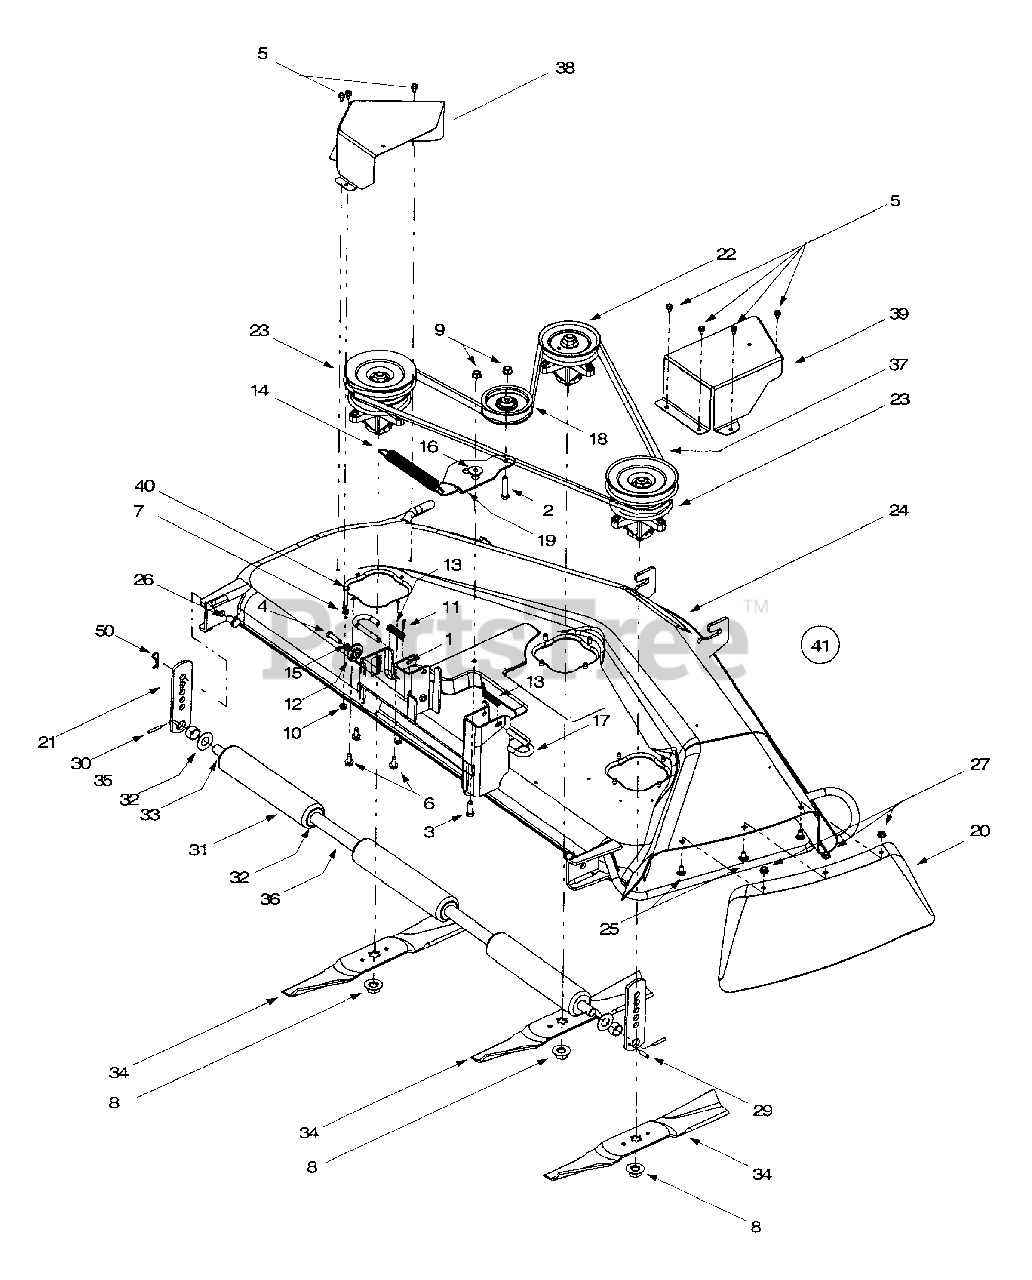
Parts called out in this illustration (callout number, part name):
1	Carriage Screw, 1/4-20 x .5
2	Hex Cap Screw, 3/8-16 x 1.75
3	Hex Cap Screw, 3/8-16 x 1.0
4	Hex Cap Screw, 5/16-18 x 1.25
5	Self Tapping Screw, 1/4-20 x .5
6	Self Tapping Screw, 5/16-18 x .75
7	Center Lock Nut, 1/4-20
8	Hex Flange Nut, 5/8-18
9	Flange Lock Nut, 3/8-16
10	Hex Flange Lock Nut, 1/4-20
11	Internal Cotter Pin, .072 x 1.12
12	Deck Adjustment Gear
13	Compression Spring, .406 x .531 x 1.75
14	Extension Spring, .91 x 7.33
15	Lock Washer, 5/16
16	Shoulder Spacer, .625 x .169
17	Deck Release Pin
18	Flat Idler Pulley, 3.5 OD
22	Center Spindle Assembly, 5 Dia.
23	Double Pulley Spindle Assembly
26	Clevis Pin, .50 Dia. x .78
27	Hex Flange Lock Nut, 5/16-18 (Grade 5)
29	Spring Pin, 1/4 Dia. x 1
30	Spring Pin, 3/16 x 1.25
31	Deck Roller
32	Flat Washer, .78 x 1.59 x .06
33	Deck Roller Shaft, .75 Dia. x 47.12
34	Blade, Star Center, 17.3
35	Spacer, .752 x 1.0 x .53
36	Spacer, .82 x 1.0 x 5.75
37	Deck Belt
12649-0638	GUARD-CHUTE - MTD/TROY-BILT RED (0638)
12649-0648	GUARD-CHUTE - TECH GRAY (0648)
12649-0650	GUARD-CHUTE - RED METALLIC (0650)
12649-0662	GUARD-CHUTE - OYSTER GRAY (0662)
12649-0665	GUARD-CHUTE - YARDMAN GREEN (0665)
12650-4008	Height Adjuster - WINE RED (4008)
